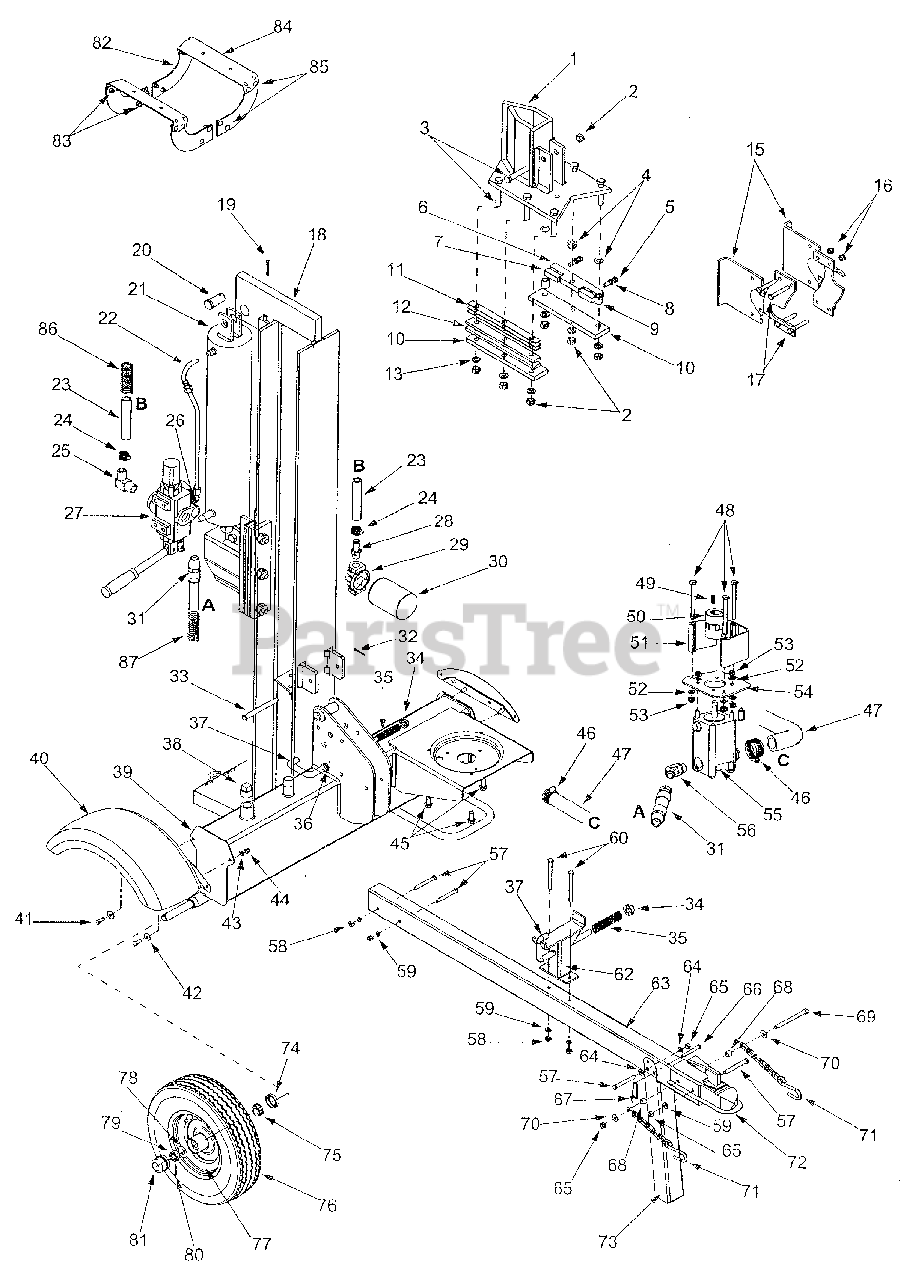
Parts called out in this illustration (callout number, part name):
2	Lock Nut 1/2-20
3	Hex Cap Screw 1/2-20 x 2.75
4	Flat Washer .531 ID x .93 OD
5	Hex Cap Screw 3/8-24 x 1.5
8	Hex Jam Nut 3/8-24
9	Spacer
13	Lock Washer 1/2
17	Hex Cap Screw 3/8-16 x 2.5
20	Clevis Pin
22	Hydraulic Tube
23	Return Hose 3/4" ID x 44" Lg.
24	Hose Clamp 5/8"
25	Return Elbow
26	90 Degree Solid Adapter
28	3/4" Hose Adapter
29	Filter Housing
30	Oil Filter
31	High Pressure Hydraulic Hose
32	Cotter Pin
33	Hinge Pin 1/2 x 4.8"
34	Push Cap
35	Compression Spring 4"
36	Flat Washer .635 ID x .93 OD
37	Locking Rod
38	Pipe Plug
39	Frame Assembly 4.0 Gal
42	Washer 5/16
43	Lock Washer 5/16
44	Hex Nut 5/16-24
45	Hex Washer Screw 3/8-16 x 1
46	Hose Clamp
47	Suction Hose
48	Hex Screw 5/16-24 x 3.25
49	Square Key 3/16" x .75
50	Flexible Coupling .750 x .500
50	Flexible Coupling .875 x .500
50	Flexible Coupling .875 x .437
51	Coupling Shield
52	Lock Washer 5/16" ID
53	Hex Nut 5/16-24
55	Gear Pump (11 gpm)
55	Pump Kit
55	Gear Pump (9.5 gpm)
56	45 Degree Elbow
57	Hex Bolt 3/8-16 x 3"
58	Hex Nut 3/8-16
59	L-Washer 3/8"
60	Hex Bolt 3/8-16 x 4"
64	Flat Washer 3/8
65	Hex Lock Nut 3/8-16
66	Clevis Pin 5/16 x 2.5"
67	Spring Pin
68	Spacer 3/8" ID x .625" OD
69	Hex Bolt 3/8-16 x 4"
70	Flat Washer 3/8" ID x .87" OD
71	Chain
72	Hitch Coupler
75	Bearing Cone
76	Wheel Assembly
77	Rim Assembly - Gray
78	Flat Washer .76" ID x 1.5" OD
79	Slotted Nut 3/4-16
80	Cotter Pin 5/32" x 1-1/4"
81	Hub Cap
85	Carriage Bolt 3/8-16 x 1.0
86	Hose Guard
87	Hose Guard
